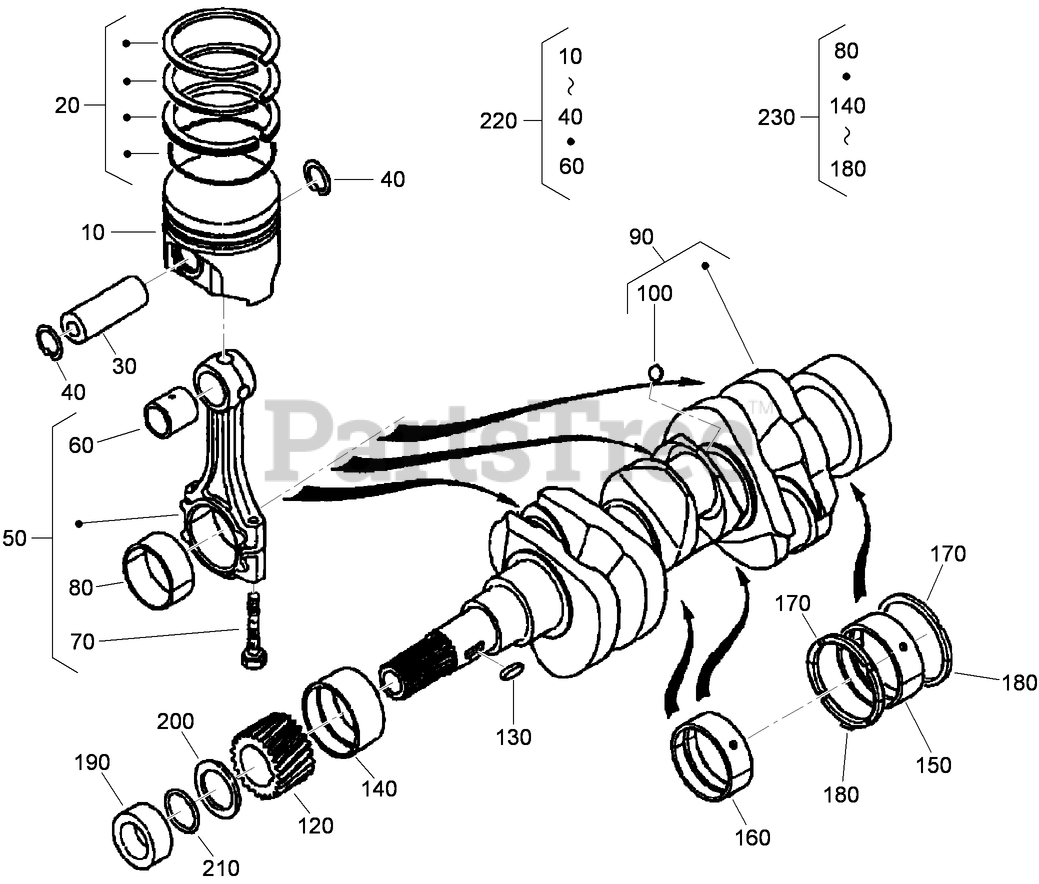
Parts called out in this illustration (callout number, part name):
10	PISTON (STD)
10	PISTON (+.25MM)
20	PISTON RING ASM (STD)
20	PISTON RING ASM (+.25MM)
30	PIN-PISTON
40	CIRCLIP-INTERNAL
50	CONNECTING ROD ASM
60	BUSHING-PIN, PISTON
70	BOLT-ROD, CONNECTING
80	METAL-CRANKPIN (STD)
80	METAL-CRANKPIN (-0.20mm)
80	METAL-CRANKPIN (-0.40mm)
90	CRANKSHAFT
120	GEAR-CRANKSHAFT
130	KEY-FEATHER
140	METAL-CRANKSHAFT (STD)
140	METAL-CRANKSHAFT (-.0.20MM)
140	METAL-CRANKSHAFT (-0.40MM)
150	CRANKSHAFT METAL ASM (STD)
150	CRANKSHAFT METAL ASM (-0.20MM)
150	CRANKSHAFT METAL ASM (-0.40MM)
160	CRANKSHAFT METAL ASM (STD)
160	CRANKSHAFT METAL ASM (-0.20MM)
160	CRANKSHAFT METAL ASM (-0.40mm)
170	METAL-SIDE (STD)
170	METAL-SIDE (+0.20MM)
170	METAL-SIDE (+0.40MM)
180	METAL-SIDE (STD)
180	METAL-SIDE (+0.20mm)
180	METAL-SIDE (+0.40mm)
190	COLLAR-CRANKSHAFT
200	SLINGER-OIL
210	O-RING
220	PISTON KIT (STD)
220	PISTON KIT (+.25MM)
230	ENGINE METAL KIT
